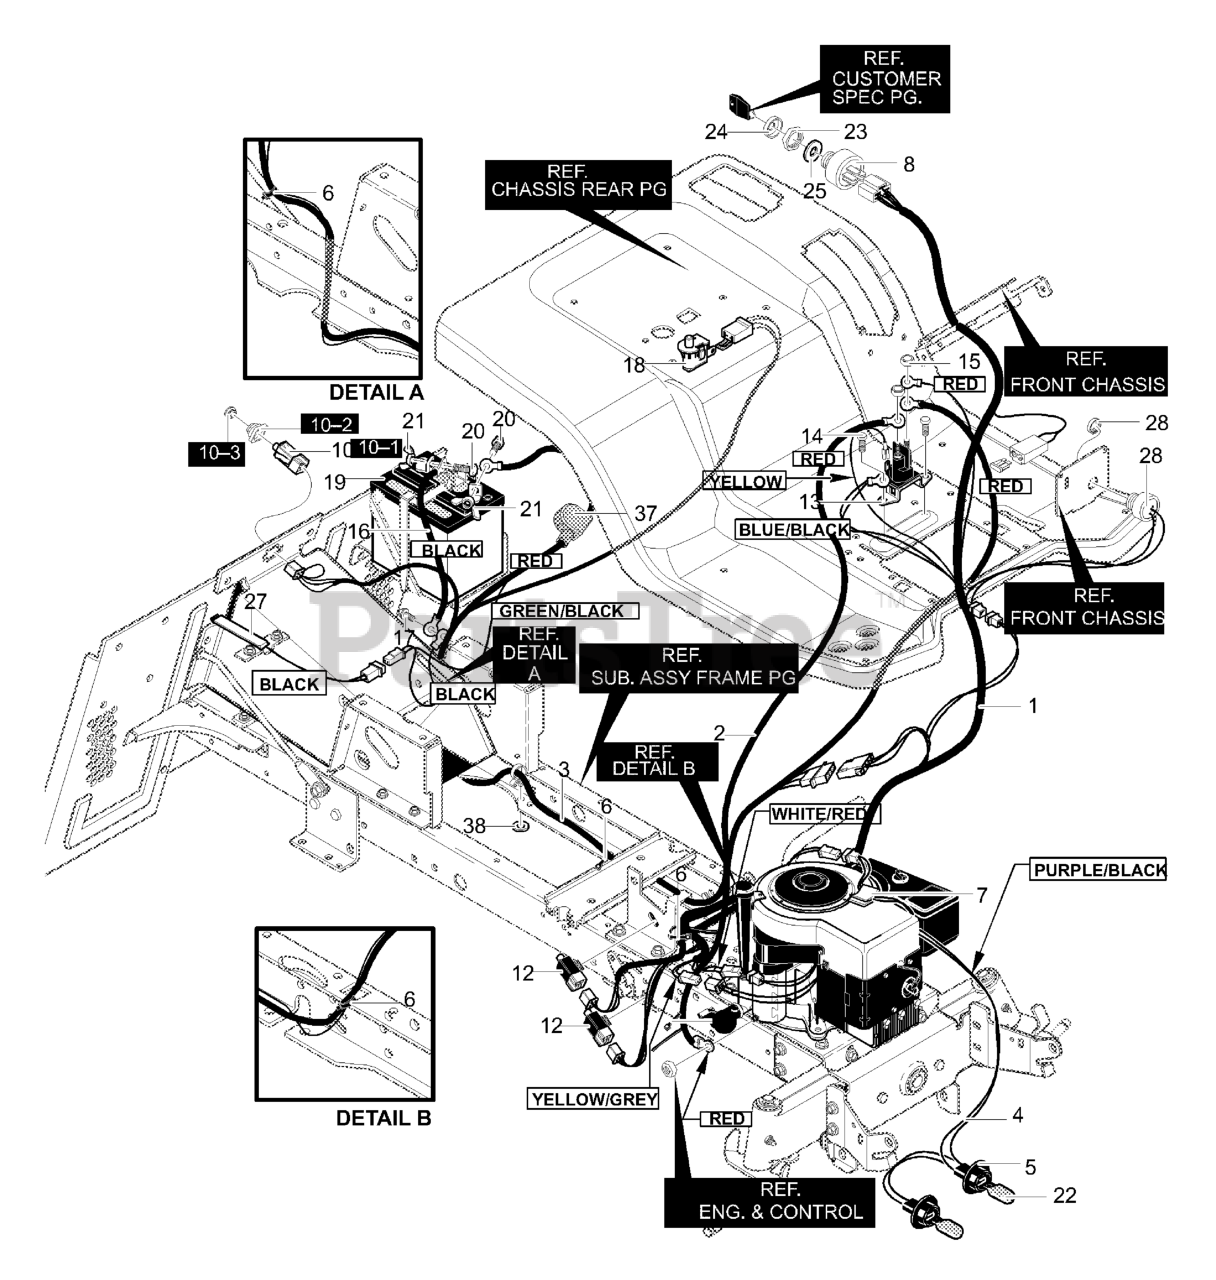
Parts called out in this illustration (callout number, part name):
1	Wire Harness
2	Wire, Lead Solenoid to Start
3	Rear Harness
4	Wire Harness, Headlight
5	Socket, Lamp
6	Cable Tie
7	Wire Clip, Adhesive
8	Switch, Ignition
10	Assy, Switch Double Pole Delta
10-1	Switch, Double
10-2	Boot, Switch
10-3	Switch Cap
12	Switch, Limit
13	Solenoid
14	Screw 1/4x.50
15	Nut, 1/4-20
16	Ground Wire
17	Screw, 1/4x.50
18	Seat Switch
19	Battery, 5 Plate
20	Bolt, 1/4-20x.63
21	Wing Nut
22	Light Bulb
23	Nut, 5/8-8 Acme Delta
24	Boot, Ign. Switch
25	Washer, Regintlk
27	Tape Switch
28	Buzzer, For Bag Full
37	Boot, Battery
38	Flatwasher
